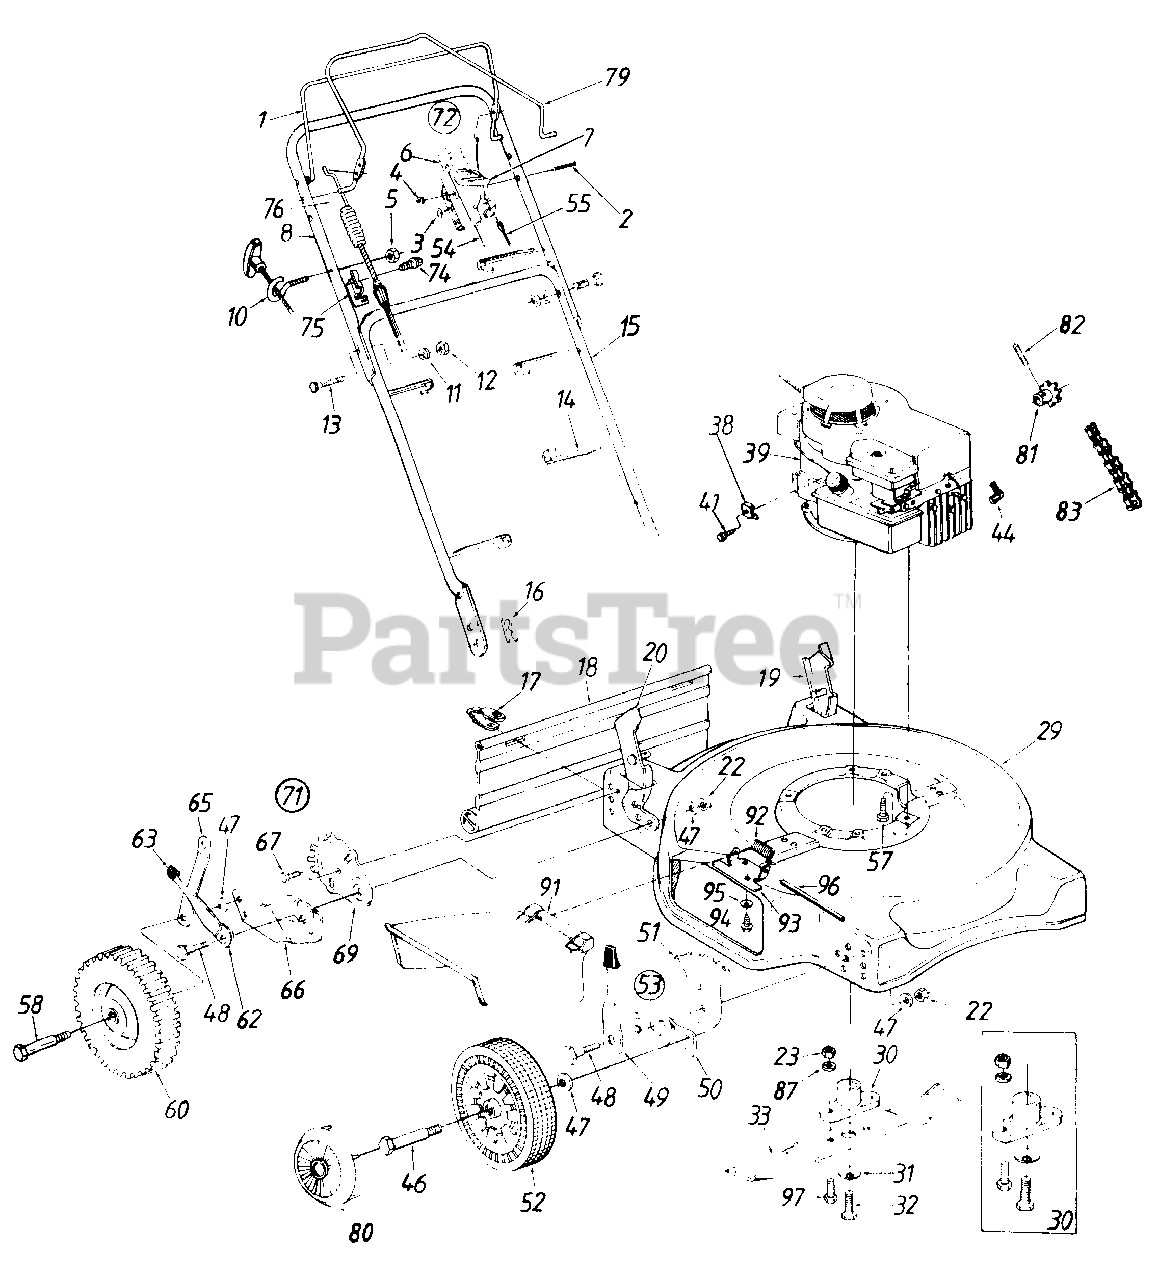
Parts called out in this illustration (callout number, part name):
2	Oval C-Sunk Mach. Scr.
3	Spr. Wash..66" I.D.
4	Hex L-Nut 1/4-20 Thd.
5	Hex L-Nut 1/4-20 Thd.
6	Throttle Body
7	Throttle Lever
11	L-Wash. 5/16" I.D.
12	Hex Nut 5/16-18 Thd.
13	Curved Carriage Bolt 5/16-18 x 1.38" Lg
14	Cable Tie
15	Lower Handle
16	Hairpin Cotter
17	Hinge Clip
18	Rear Flap
19	Handle Bracket Ass'y.- L.H.
20	Handle Bracket Ass'y.- R.H.
22	Hex Nut 3/8-16 Thd.
23	Hex Nut 3/8-24 Thd.
29	22" Deck Ass'y.
30	Blade Adapter Kit
31	Bell-Wash..39" I.D.
32	Hex Bolt 3/8-24 x 1.5" Lg.
33	22" Blade
38	Cable Clamp (B&S)
39	Engine
41	Hex Wash. Hd. Scr. #10-32 x .62" Lg. (B&S)
44	Spark Plug Boot
46	Front Axle Bolt
47	Bell-Wash..400" I.D. x .88"
48	Shld. Bolt .50" Dia. x .357"
49	Spring Lever Ass'y. w/Knob
51	Height Adj. Plate
52	Front Wheel Ass'y. Comp.
53	Height Adj. Ass'y. Comp.- R.H.
54	Throttle Control Wire 51" Lg.
55	Control Cable - 39"
57	Hex L-Wash. Hd. Scr. 3/8-16 x 10" Lg
58	Rear Axle Bolt
60	Rear Wheel Ass'y. Comp.
62	Spring Lever
63	Spring Lever Knob
67	Hex AB-Tap 1/4-.62" Lg.
69	Index Plate
71	Rear Height Adj. Ass'y.- R.H.
72	Throttle Box Comp.
74	Hex Wash. AB-Tap Scr. 5/16 x .75" Lg
75	Cable Brkt.
76	Clutch Cable
81	10 Tooth Sprocket Ass'y.
82	Spring Pin Spir. 3/16" Dia. x 1" Lg
83	#48 Chain 1/2" Pitch 50 Links (Endless)
87	L-Wash. 3/8" I.D.
91	Chute Deflector Ass'y.
92	Torsion Spring
93	Adapter Plate
94	Hex Self-Tap Scr. 1/4-20 x .5" Lg
95	Bell-Wash. 1/4" I.D.
96	Hinge Pin
97	Hex Bolt 3/8-24 x 1" Lg.
